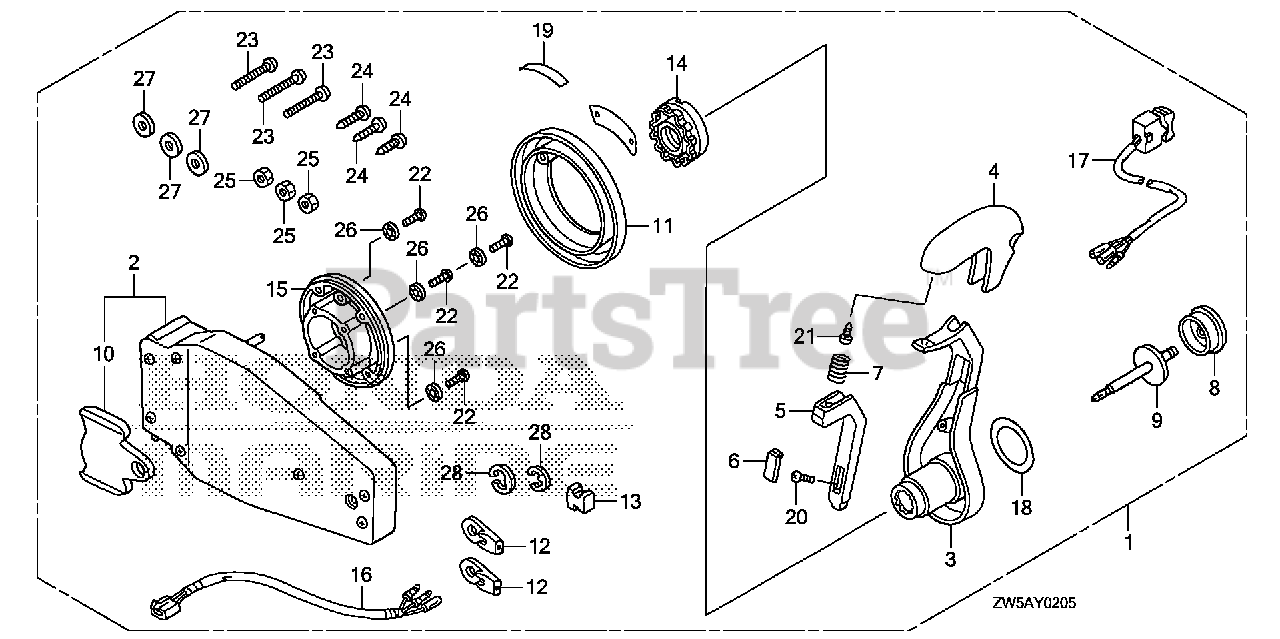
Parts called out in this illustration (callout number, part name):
1	BOX KIT, REMOTE CONTROL (FLUSH MOUNT)(L)
2	HOUSING ASSY., L. (INNER) (FLUSH MOUNT)
3	HANDLE, REMOTE CONTROL
4	COVER, GRIP
5	ARM, NEUTRAL LOCK
6	COVER, LOCK ARM
7	SPRING, NEUTRAL LOCK ARM
8	BUTTON, THROTTLE
9	SHAFT, THROTTLE BUTTON
10	PLATE, DWELL
11	COVER ASSY.
12	TERMINAL, CABLE
13	SPACER, CABLE CLAMP
14	HOLDER, NEUTRAL LOCK
15	BASE
16	SUB-HARNESS ASSY., POWER TRIM-TILT (C)
17	SWITCH ASSY., POWER TRIM-TILT (C)
18	MARK, HANDLE FLUSH MOUNT
19	MARK, FLUSH MOUNT
20	SCREW, TRUSS (4X12)
21	SCREW, PAN (5X16)
22	SCREW, PAN (5X30)
23	SCREW, PAN (6X35)
24	SCREW, TAPPING (6X30)
25	NUT, HEX. (6MM)
26	WASHER, LOCK (5MM)
27	WASHER, PLAIN (6MM)
28	E-RING (6MM)
